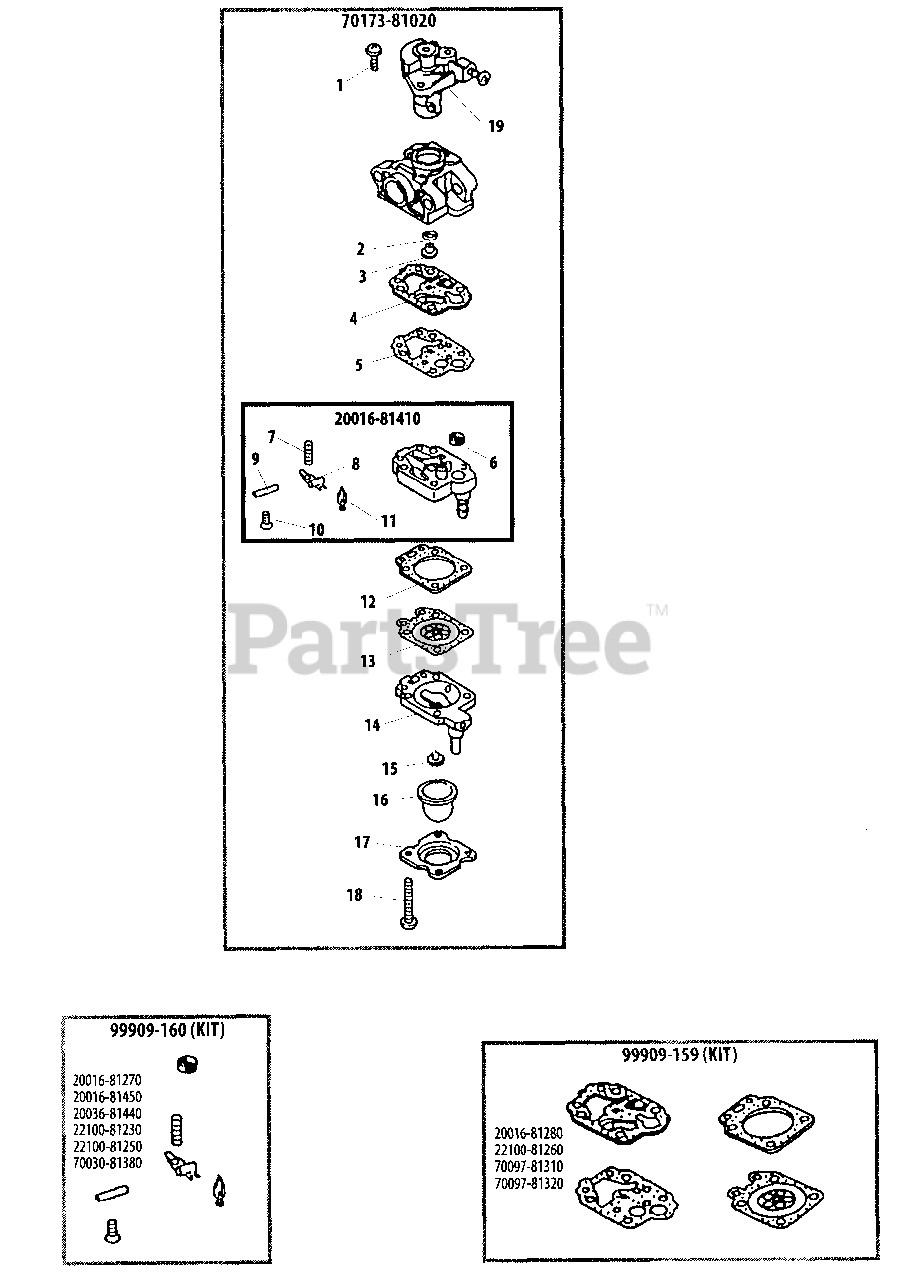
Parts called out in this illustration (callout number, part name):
1	SCREW
2	O-RING
3	JET, MAIN - 38
4	GASKET, PUMP
5	DIAPHRAGM, PUMP
6	STRAINER
7	SPRING, METERING LEVER
8	LEVER, METERING
9	PIN, METERING LEVER
10	SCREW, METERING LEVER PIN
11	VALVE, INLET NEEDLE
12	GASKET, METERING
13	DIAPHRAGM, METERING
14	BASE, PURGE
15	VALVE, CHECK
16	BULB, PURGE
17	RETAINER, PURGE BULB
18	SCREW, PUMP COVER
19	THROTTLE VALVE ASSY
20016-81410	PUMP BODY ASSY
70173-81020	CARBURETOR
99909-159	DIAPHRAGM/GASKET KIT
99909-160	REPAIR KIT
